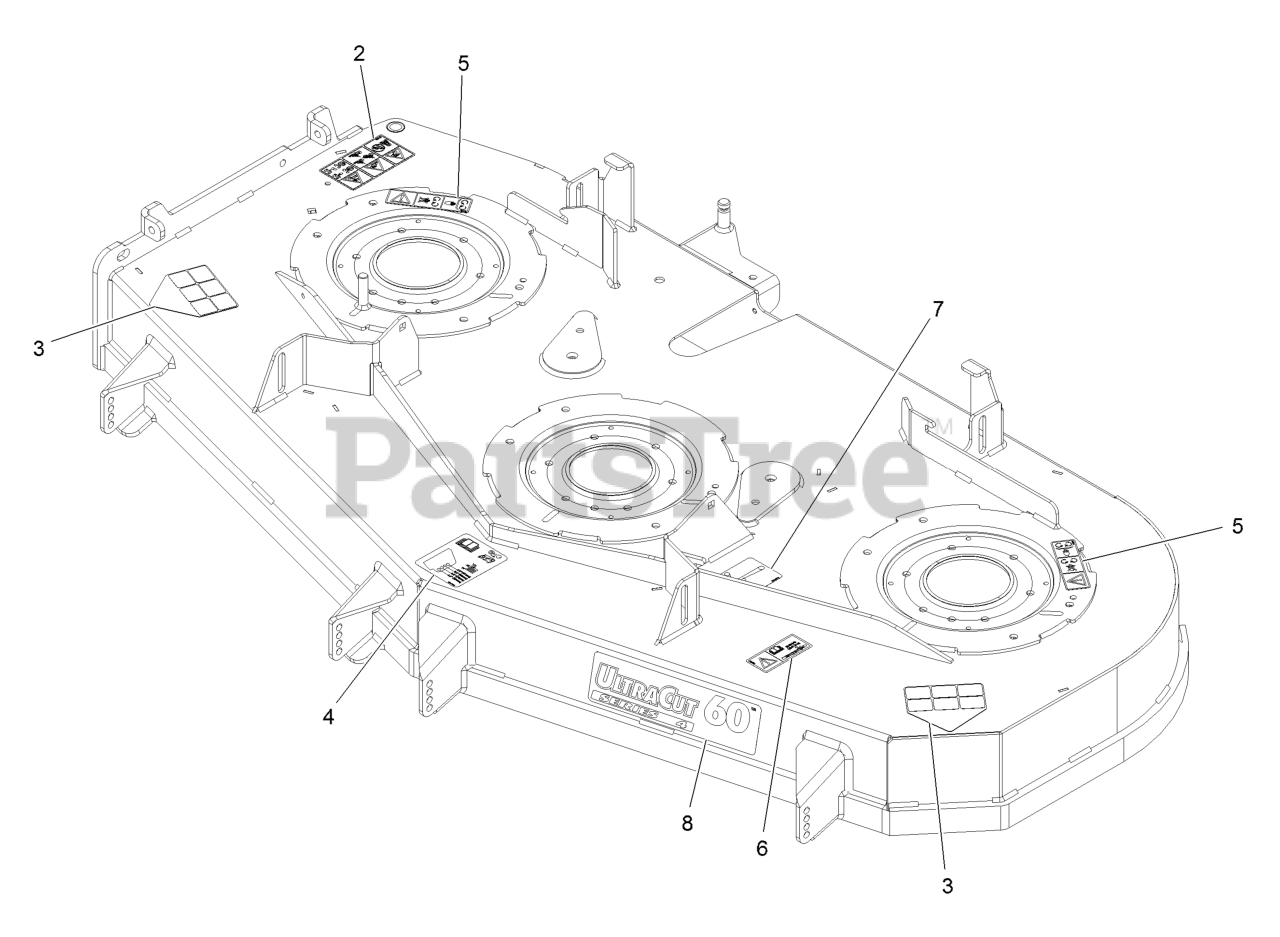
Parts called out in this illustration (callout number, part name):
2	DECAL-DANGER
3	DECAL-DANGER
4	DECAL-ROLLER, ANTI-SCALP
5	DECAL-COVER, MISSING
6	DECAL-TORQUE, BOLT
7	DECAL-ROUTING, BELT
8	DECAL,ULTRACUT 60 SERIES 4
